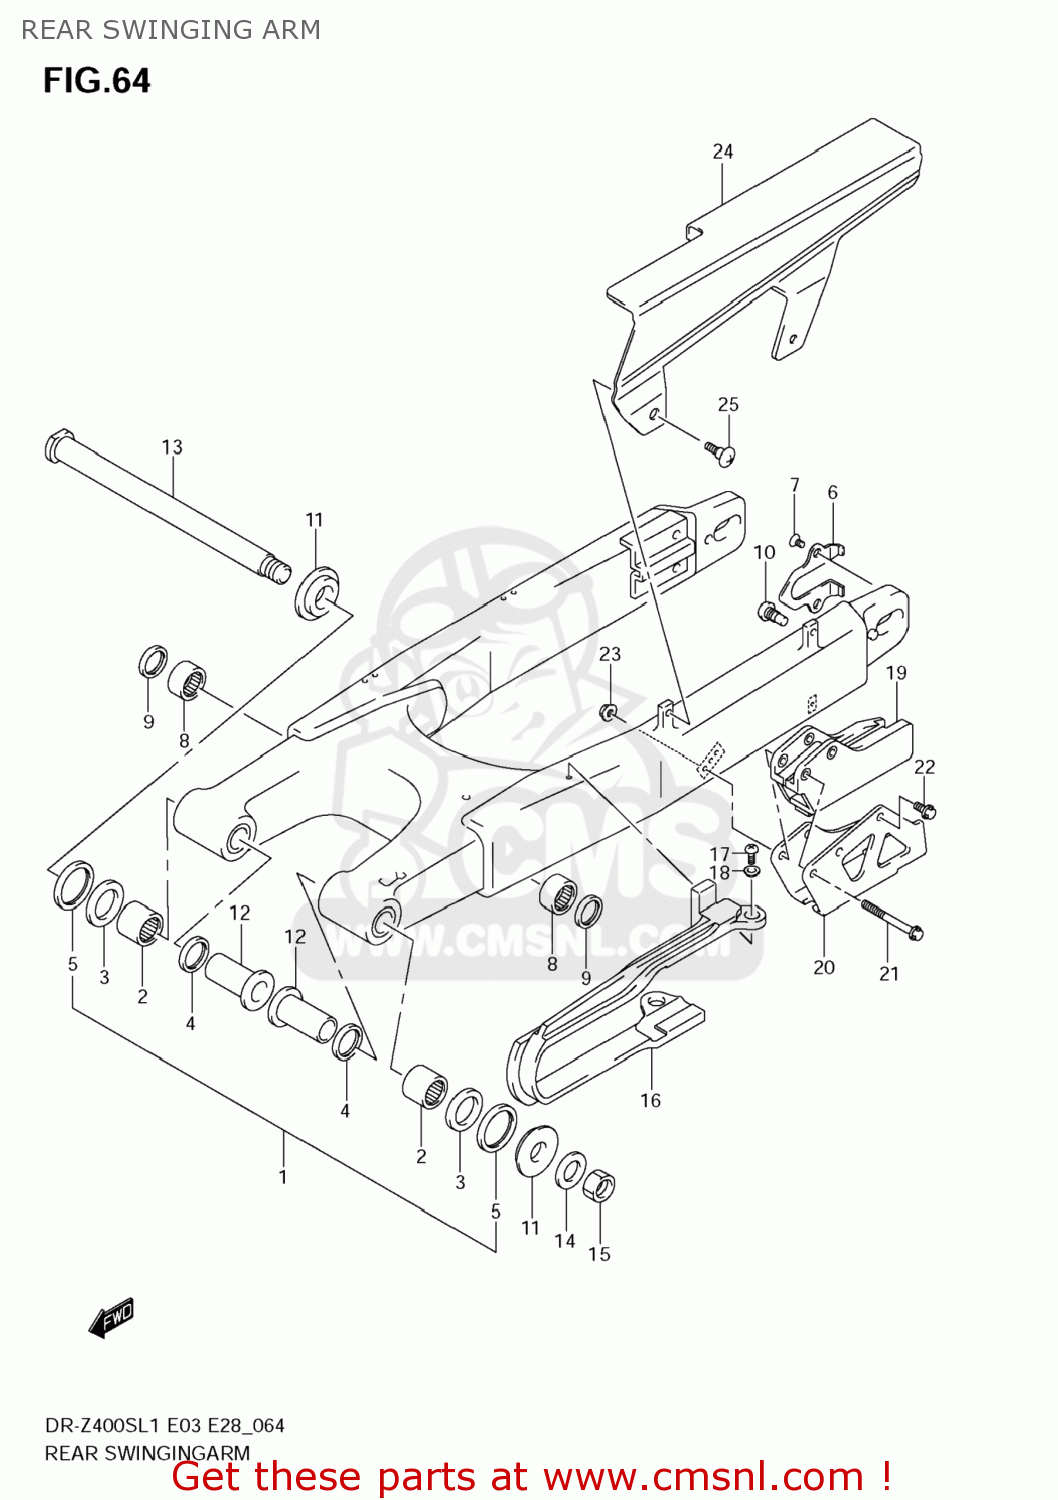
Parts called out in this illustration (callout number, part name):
1	SWING ARM ASSEMBLY,REAR
2	BEARING(22X29X30)
3	BEARING(22X35X2)
4	SEAL,OIL(22X29X4)
5	SEAL,RR SWGARM PIVOT OUTER
6	PLATE,RR SWING ARM AXLE
7	SCREW(5X8)
8	BEARING(20X27X15)
9	SEAL,CUSHION LEVER DUST
10	STOPPER,CHAIN ADJUSTER
11	SPACER,SWINGINGARM PIVOT OUTER
12	SPACER,SWGARM PIVOT INNER
13	SHAFT,RR SWINGINGARM PIVOT
14	WASHER
15	NUT
16	BUFFER,CHAIN TOUCH DEFENSE
17	SCREW
18	WASHER
19	GUIDE,CHAIN
20	PLATE,CHAIN GUIDE
21	BOLT
22	BOLT
23	NUT
24	CASE,CHAIN
25	SCREW(6X16)
